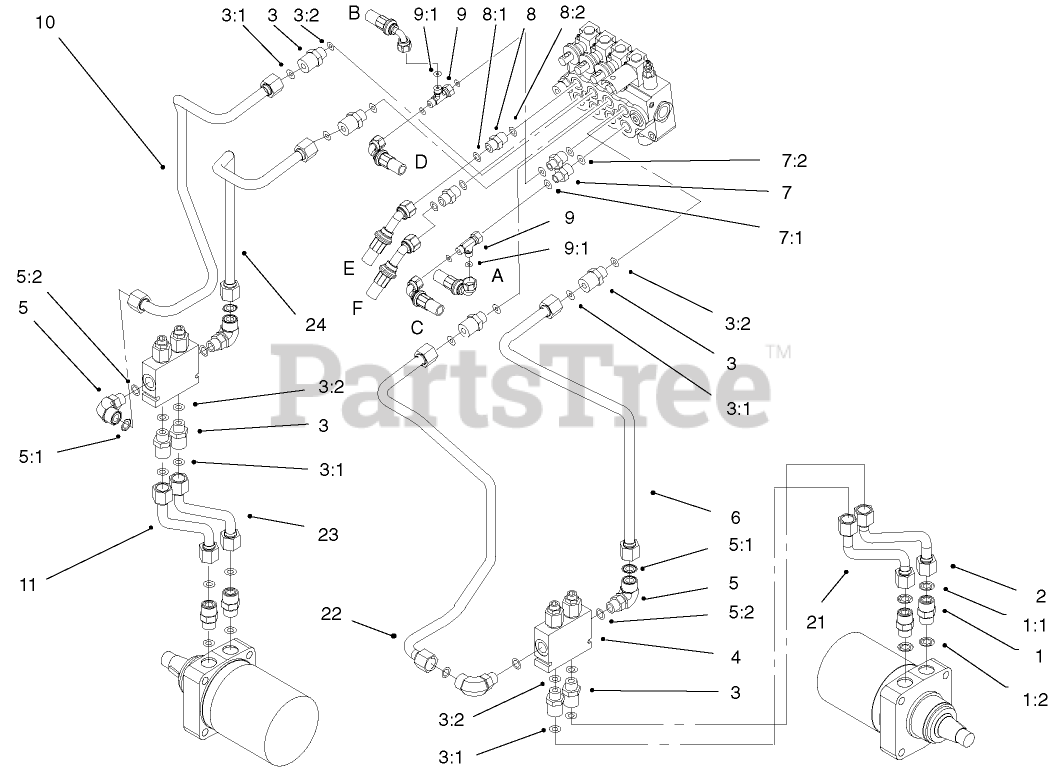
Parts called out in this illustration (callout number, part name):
1	FITTING-STRAIGHT
1:1	O-RING
1:2	O-RING
2	TUBE-HYD
3	FITTING-STR
3:1	O-RING
3:2	O-RING
4	VALVE-COUNTERBALANCE
5	Fitting-Elbow, 90 DEG
5:1	O-RING
5:2	O-RING
6	TUBE-HYD
7	FITTING-STR
7:1	O-Ring
7:2	O-RING
8	FITTING-STRAIGHT
8:1	O-RING
8:2	O-RING
9	FITTING-HYD
9:1	O-RING
10	TUBE-HYD
11	TUBE-HYD
21	TUBE-HYD
22	TUBE-HYD
23	TUBE-HYD
24	TUBE-HYD
